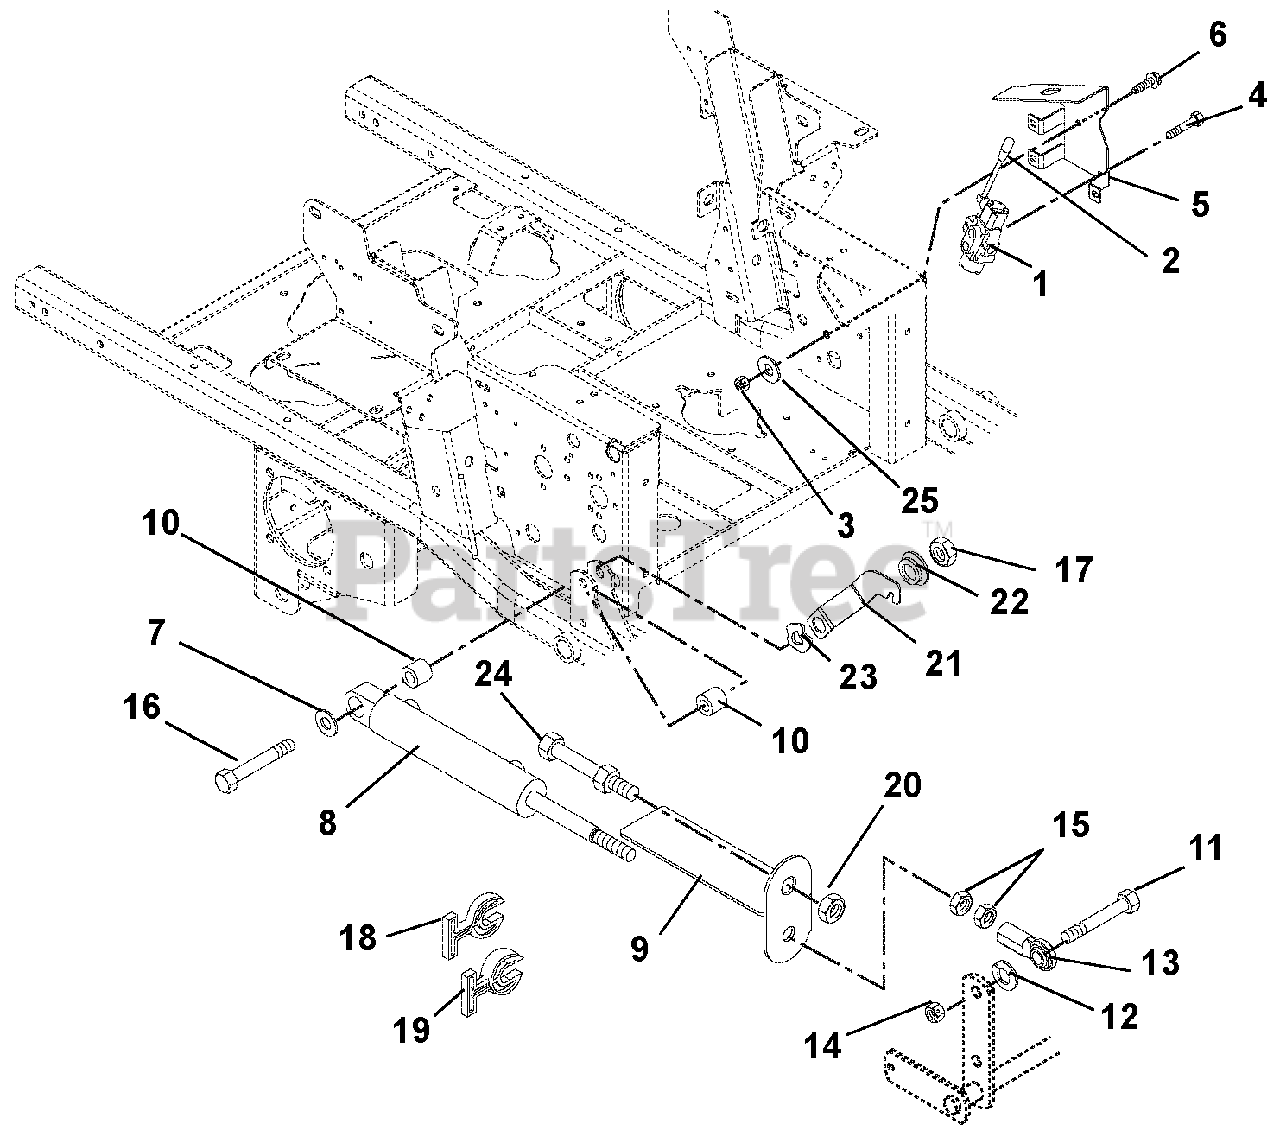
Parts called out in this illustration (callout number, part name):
1	Valve, Hydraulic Lift
2	Knob
3	Nut, Locking Center .31-18
4	Bolt, Hex .31-18 x 2.0 Grade 5
5	Bracket, Valve Mounting
6	Screw, Tapping .38-16 x .50 Hex Washer Head
7	Washer, Flat Steel .515 x 1.625 x .25
8	Cylinder, Hydraulic Lift
9	Strap, Cut Indicator / Guard
10	Bushing .516 x 1.00 x 1.05
11	Bolt, Hex .62-11 x 2.25 Grade 8
12	Washer, Lock .62 x .156
13	Rod End, Right Hand Female .625
14	Nut, Locking Center .62-11
15	Nut, Jam .625-18
16	Bolt, Hex .50-13 x 3.75 Grade 5
17	Nut, Locking Top Flange .50-13
18	Stop, Cylinder .34 Thick
19	Stop, Cylinder .68 Thick
20	Nut, Jam .75-16
21	Latch, Footboard
22	Bushing, Flange .515 x .75 x .275 x 1.12
23	Washer, Wave .076 x 1.12 x .08
25	Washer, Locking .31 x .078 Regular
